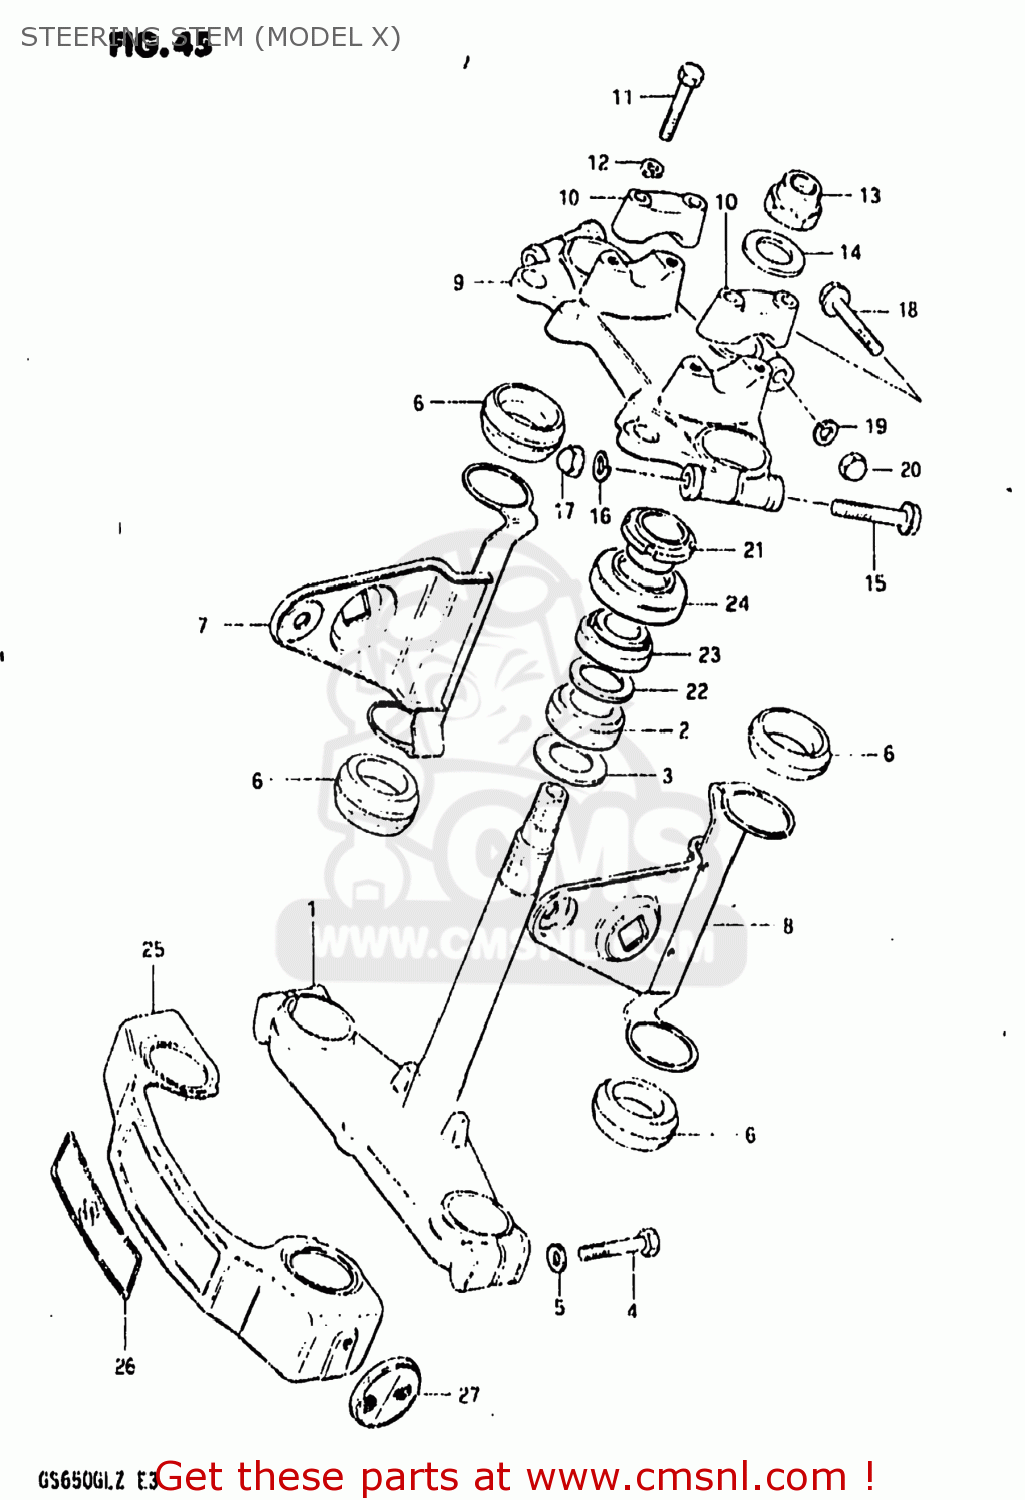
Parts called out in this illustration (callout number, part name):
1	STEM,STEERING
2	BEARING
3	WASHER,THRUST
4	BOLT 8X45
5	WASHER,LOCK,8.
6	CUSHION,HEADLAMP BRACKET
7	BRACKET,HEADLAMP,RIGHT
8	BRACKET,HEADLAMP,LEFT
9	HEAD,STEERING STEM
10	HOLDER,HANDLE UPR
11	BOLT
12	LOCK WASHER
13	NUT,FR FORK UPR BRACKET
14	WASHER
15	BOLT 10X55
16	LOCK WASHER
17	NUT
18	BOLT
19	LOCK WASHER
20	NUT
21	NUT,STEERING STEM
22	WASHER(18.5X24X1)
23	TAPER,ROLLER BEARING
24	DUST SEAL,STEERING,UPPER
25	COVER,FRONT FORK
26	EMBLEM,FR FORK COVER
27	REFLEX REFLECTOR,RR
